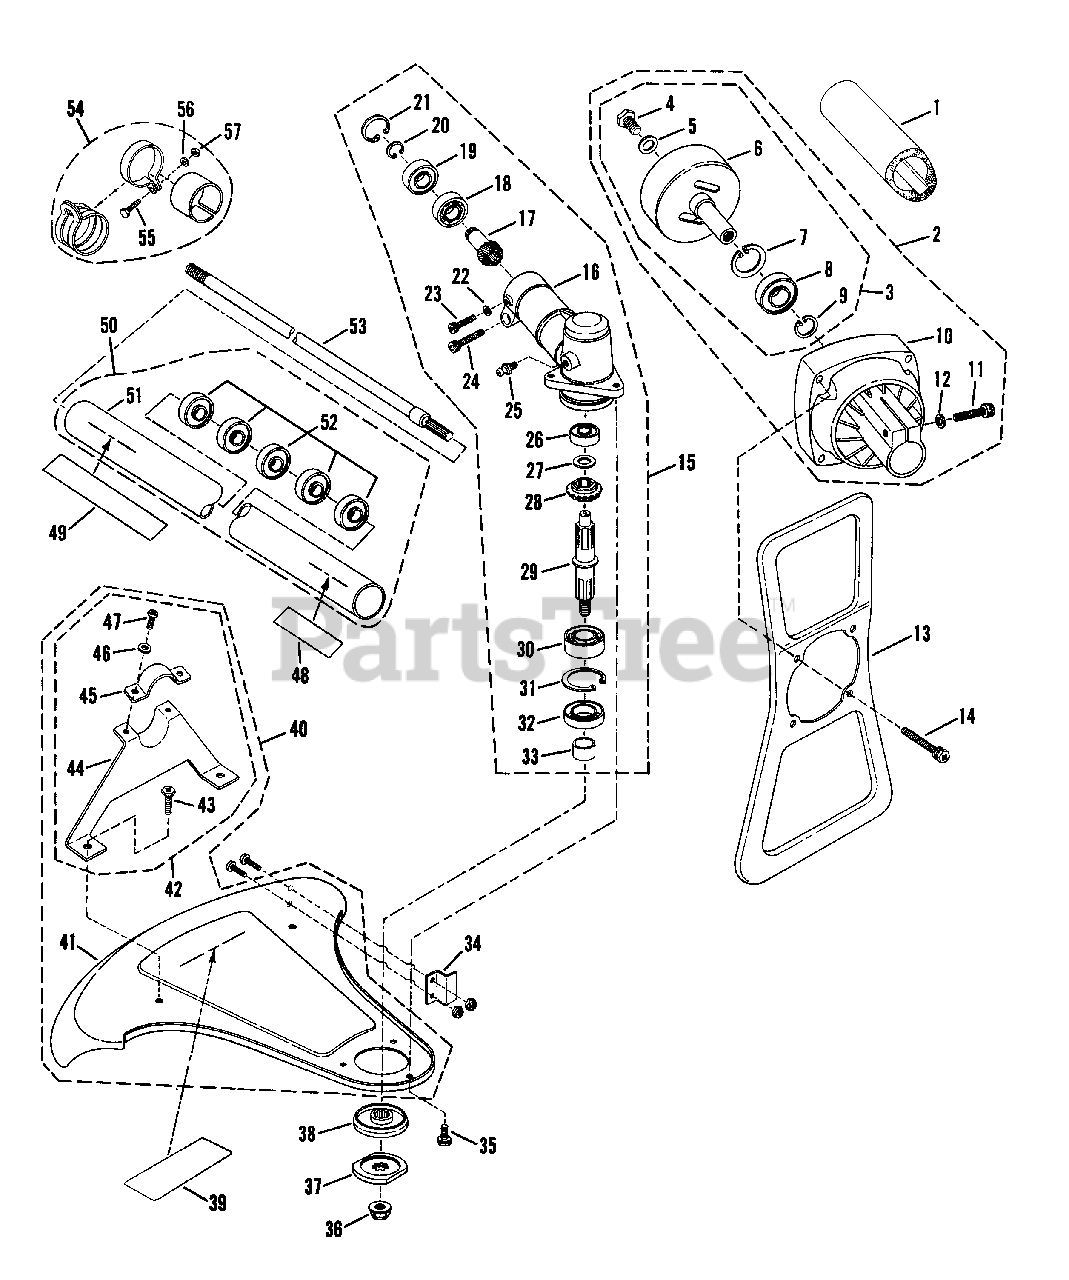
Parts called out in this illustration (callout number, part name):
1	PROTECTOR/HIP PAD
2	CLUTCH CASE ASSM'Y.
3	CLUTCH DRUM ASSM'Y.
4	BOLT, Hex Hd.
6	DRUM, Clutch
7	SNAP RING
8	BEARING
9	SNAP RING
10	CASE, Clutch
11	SCREW, M6 x 25mm, Socket
12	LOCKWASHER
14	BOLT, M6 x 35mm, Hex
15	GEAR HEAD ASSM'Y.
16	GEAR CASE
17	BEVEL PINION
18	BEARING
19	BEARING
20	SNAP RING
21	SNAP RING
22	LOCKWASHER
23	SCREW, M5 x 15mm, Socket
24	SCREW, M6 x 20mm, Socket
25	FITTING, Lube
26	BEARING
27	WASHER, Thrust
28	BEVEL GEAR
29	SPLINE SHAFT
30	BEARING
31	SNAP RING
32	SEAL, Oil
33	SPLINE SLEEVE
34	LINE CUTTER KIT (Hdwr. Incl.)
35	BOLT, M5 x 10mm, Hex
36	LOCKNUT, M10
37	HOLDER (B)
38	HOLDER (A)
39	DECAL-WARNING (Shield)
40	SHIELD-BRACE ASSM'Y.
41	SHIELD
42	BRACE ASSM'Y. Shield
43	BOLT, M6 x 12mm, Hex
44	BRACE, Shield
45	BAND, Shield Brace
47	SCREW, M6 x 20mm
48	DECAL-WARNING (Eye Protection)
49	DECAL-SNAPPER
50	ASSEMBLY, Tubing & Bushings
51	TUBING
52	BUSHING
53	SHAFT, Tubing
54	HANGER, Band Assm'y.
55	BOLT, M5 x 15mm Hex
56	LOCKWASHER
57	NUT, M5 Hex
